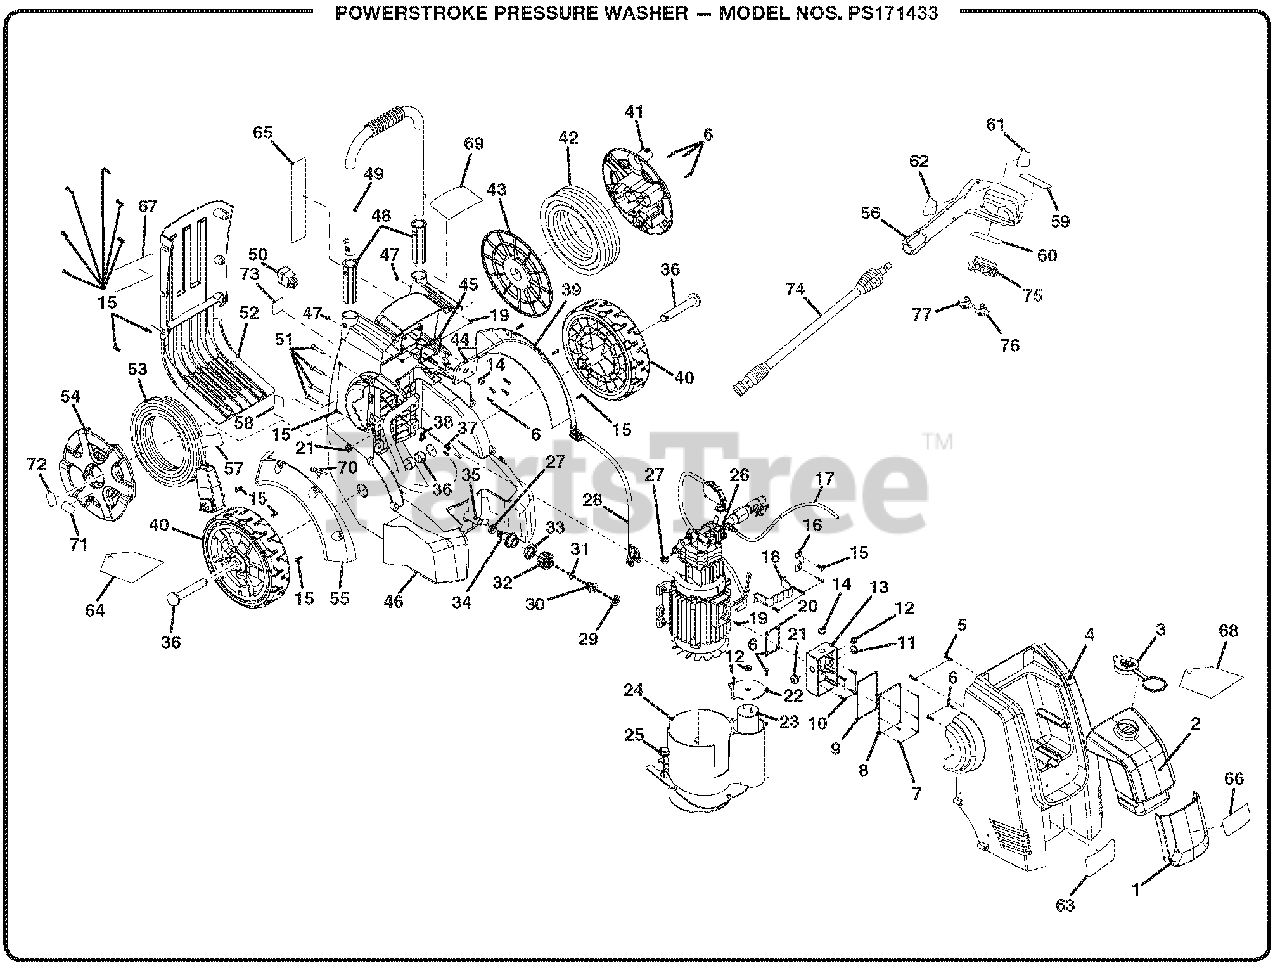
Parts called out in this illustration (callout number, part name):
1	Tank Front Panel
4	Front Housing
5	Screw (M4.2 x 25 mm)
6	Screw (M4.2 x 15 mm)
7	Screw (M2.9 x 10 mm)
8	Junction Box Cover
9	Junction Box Gasket
10	Screw (M4 x 10 mm)
11	Grommet (1)
12	Grommet (4)
13	Junction Box
14	Grommet (3)
15	Screw (M5 x 16 mm)
17	Detergent Hose
18	Pump Clamp
19	Screw (M4 x 6 mm)
21	Grommet (2)
22	Capacitor Box Cover
23	Capacitor
24	Motor Cover
26	Motor Pump Assembly
28	Inner Cable
29	Water Inlet Filter
30	Water Inlet Screw
31	O-Ring (13.5 x 1.8G)
32	Water Inlet Screw Nut
34	Hose Connector
35	Water Inlet Hose
37	Screw (M4.2 x 10 mm)
38	Cord Clamp
39	Right Fender
40	Wheel Assembly
41	High Pressure Hose Reel Cover
42	High Pressure Hose
43	High Pressure Hose Reel
44	Switch Cover
46	Back Housing
47	Lock Nut (M4)
48	Handle Guide Bushing
49	Handle Assembly
50	Switch (20A)
51	Screw (M6 x 20 mm)
52	Back Shroud
53	Power Cord
54	Power Cord Reel Cover
55	Left Fender
56	Trigger Handle Assembly
57	Danger Cord Wrap Label
58	Data Label
59	Trigger Handle Warning Label
60	Trigger Handle Rating Label
61	Trigger Handle Warning Label (French/Spanish)
62	Trigger Handle Logo Label
63	Performance Label
64	Power Cord Reel Hang Tag
65	Starting Label
66	Front Logo Label
67	Danger Label
68	Detergent Tank Hang Tag
69	Top Logo Label
71	Power Cord Reel Unlock Label
72	Power Cord Reel Lock Label
73	On/Off Switch Label
74	Spray Wand
75	Nozzle Holder
76	25deg Nozzle
77	Soap Nozzle
